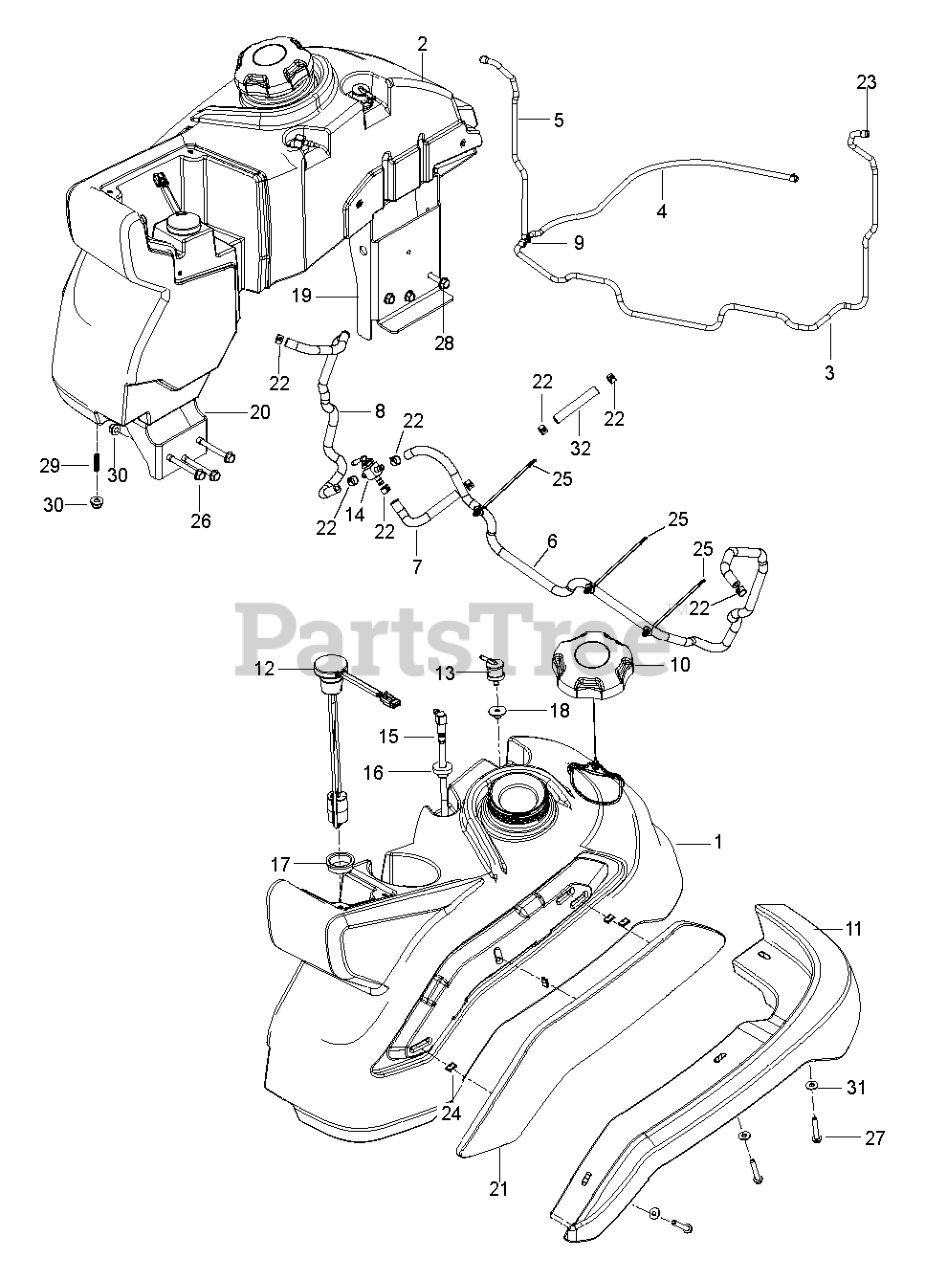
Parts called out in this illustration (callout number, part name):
1	TANK UNIT ASSY LH 2018 PROD. Y
2	TANK UNIT ASSY RH 2018 PROD. Y
3	HOSE 3/16" VAPOR LINE 41" LENG
4	HOSE.3/16".VAPOR.LINE.23"LGTH
5	HOSE.3/16".VAPOR.LINE.17"LGTH
6	HOSE 1/4" LOW PERMEATION FUEL
8	HOSE.1/4".LOW.PERM.FUEL.LN.24"
9	TEE, FUEL LINE 3/16"
10	CAP, FUEL
11	GUARD.MUD.LH
12	SENSOR.FUEL.LVL.FLOAT.V500
13	VALVE.FUEL.CHECK
14	FUEL VALVE
15	TUBE.ASM.FUEL.TANK.PICK-UP.LH
16	BUSHING OUTLET T
17	GROMMET, FUEL SENSOR
18	GROMMET.CHECK.FUEL
19	BRACKET.FUEL.TANK.REAR.SUP.431
20	BRACKET.FUEL.TANK.REAR.SUP.431
21	COVER.LH.FUEL.TANK/CONSOLE APP
22	HOSE CLAMP
23	CLAMP, HOSE
24	CLIP.U-TYPE
25	CABLE.TIE.6".FIRTREE.PZ.REFRES
26	BOLT HEX FLGHD 5/16-18X3 GR. 5
27	SCREW.1/4-20X1.5IN.HEX.MACH
28	SCREW
29	SCREW.5/16-18X1.25"THREADED
30	5/16-18 NYLOC FLANGE NUT
31	WASHER
32	HOSE.1/4".LOW.PERM.FUEL.LN.3"
